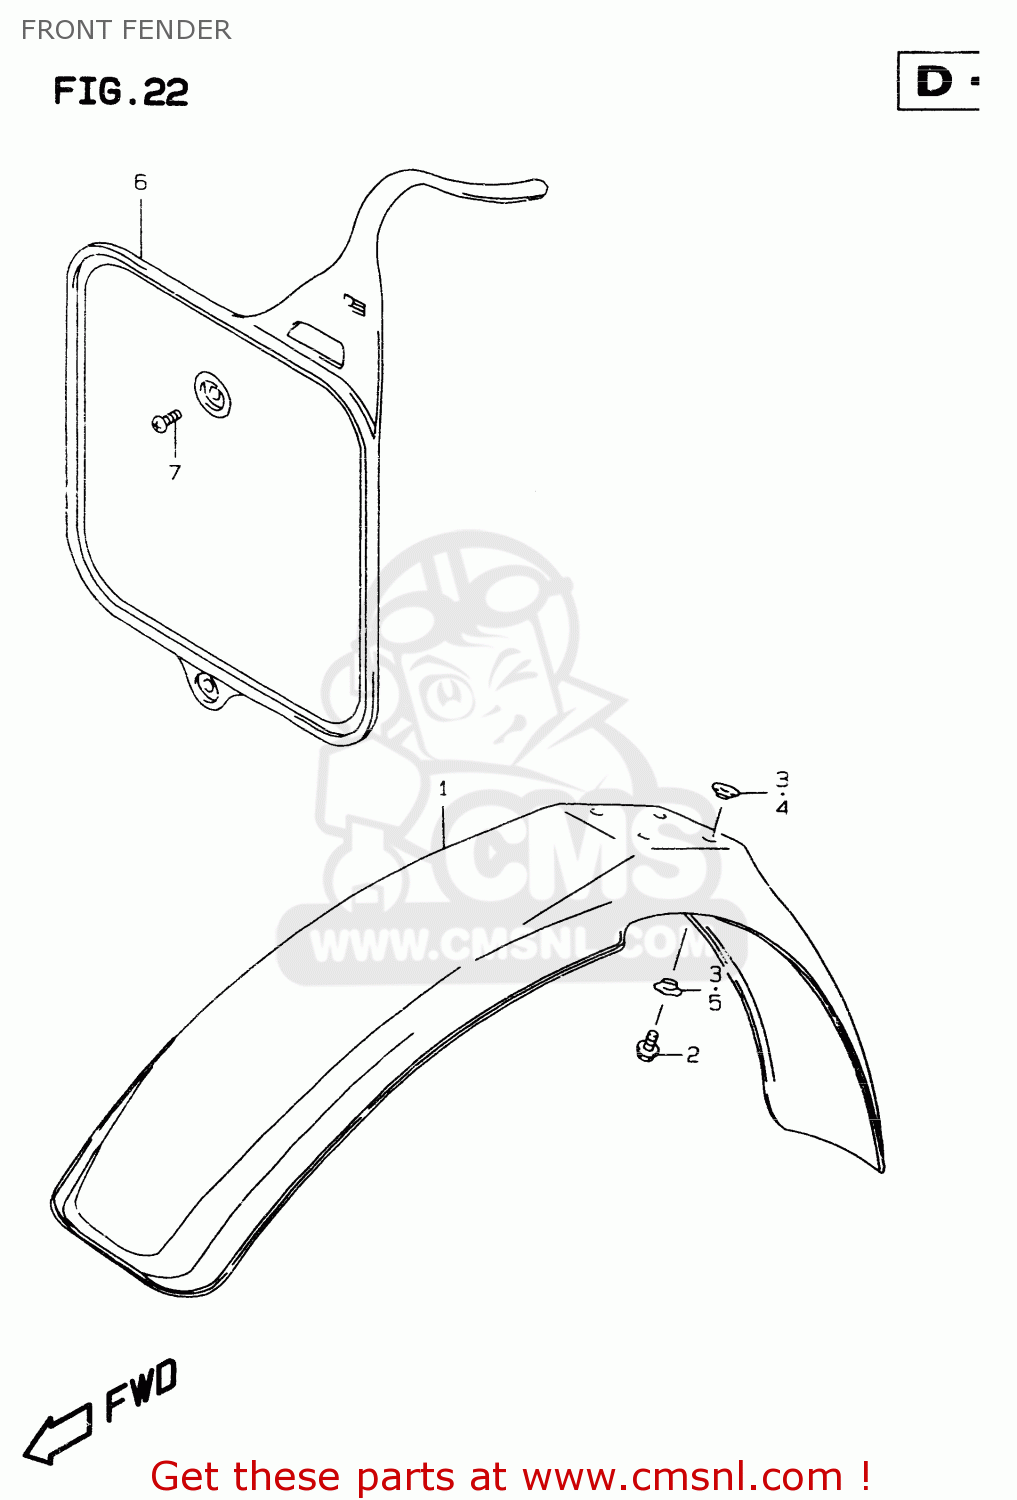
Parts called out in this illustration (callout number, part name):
1	FENDER,FRONT
2	BOLT
3	WASHER
4	WASHER
5	WASHER
6	PLATE,NUMBER FR
7	SCREW
